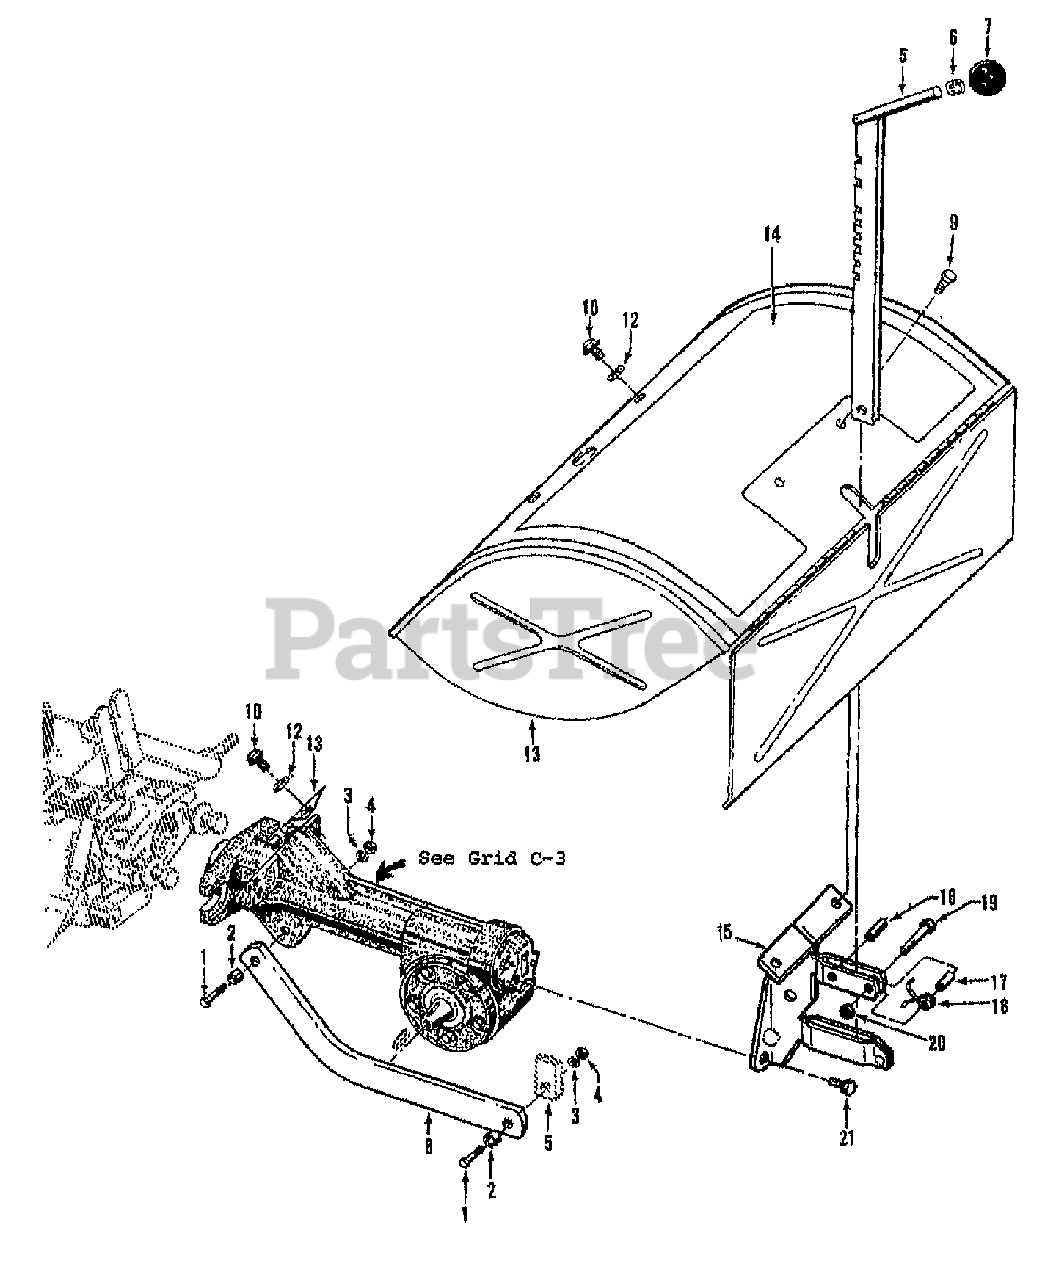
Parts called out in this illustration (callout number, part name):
1	SCR-HH 3/8-16X1.25
2	BUSHING-.5X.375X.3
3	WASHER-LK .375 @ DEPL
4	NUT-HEX 3/8-16 ZP
5	DEPTH REGULATOR W/KNOB
6	RING-TOLERANCE .5325 ID
7	KNOB-CONTROL
8	BAR-DRAG RED
9	SCR-HWH 1/4-20 X .5 STH
10	SCR-HFLK 5/16-18X.75 ZP
11	THIS REF. NO. NOT USED
12	WASHER-#1.125X.344 ZP
13	HOOD W/DECALS OPC SERVICE
14	DECAL-HOOD INST
15	BRKT W/ROLL PIN (9308)
16	PIN-ROLL .25 X 1
17	SPACER-.250X.343X.375
18	SPRING-TORSION
19	SCR-HH 1/4-20X1.0
20	NUT-LK 1/4-20
21	SCR-HFLK 5/16-18X.62 G5ZP
